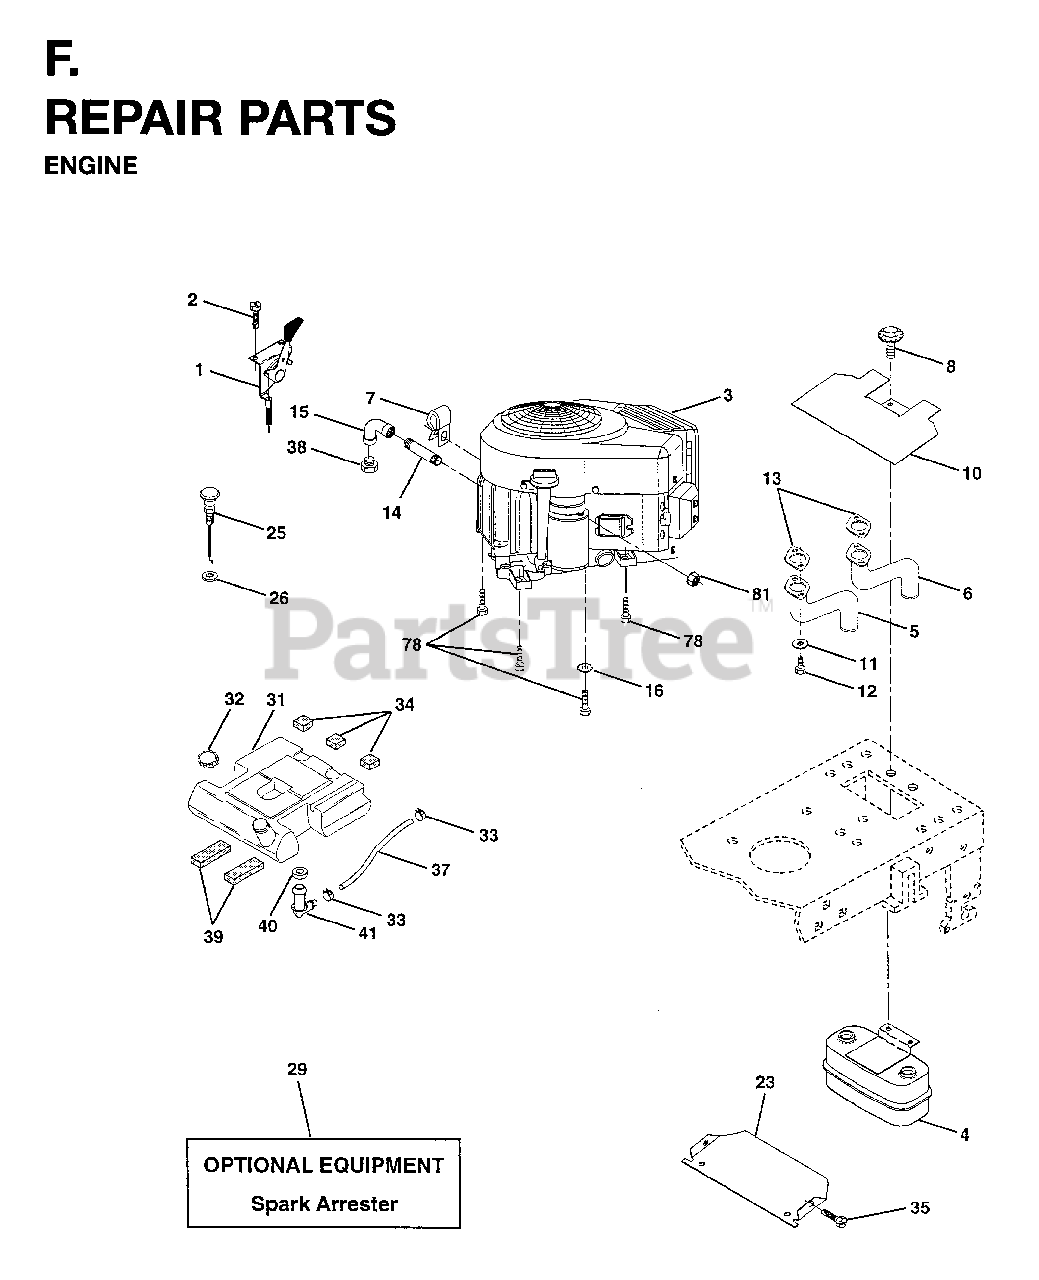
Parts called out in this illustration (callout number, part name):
1	CONTROL THROTTLE 36"
2	BOLT
4	MUFFLER.TWIN.CYL.LOW.TONE
5	TUBE ASSY EXH LH
6	TUBE ASSY EXH RH
8	BOLT
10	SHIELD HEAT LT
14	PIPE NIPPLE LT
15	ELBOW
16	WASHER, LOCK 3/8
23	HEAT SHIELD
25	CONTROL, CHOKE
26	NUT KEPS 3/8 - 24 UNF
29	ARRESTER SPARK (OPTIONAL)
31	FUEL TANK REAR YT/GT
32	FUEL CAP
33	HOSE CLAMP
34	PAD-SPACER LT
39	PAD IDLER TI
40	BUSHING OUTLET T
41	STEM FUEL TANK
78	BOLT
81	NUT
